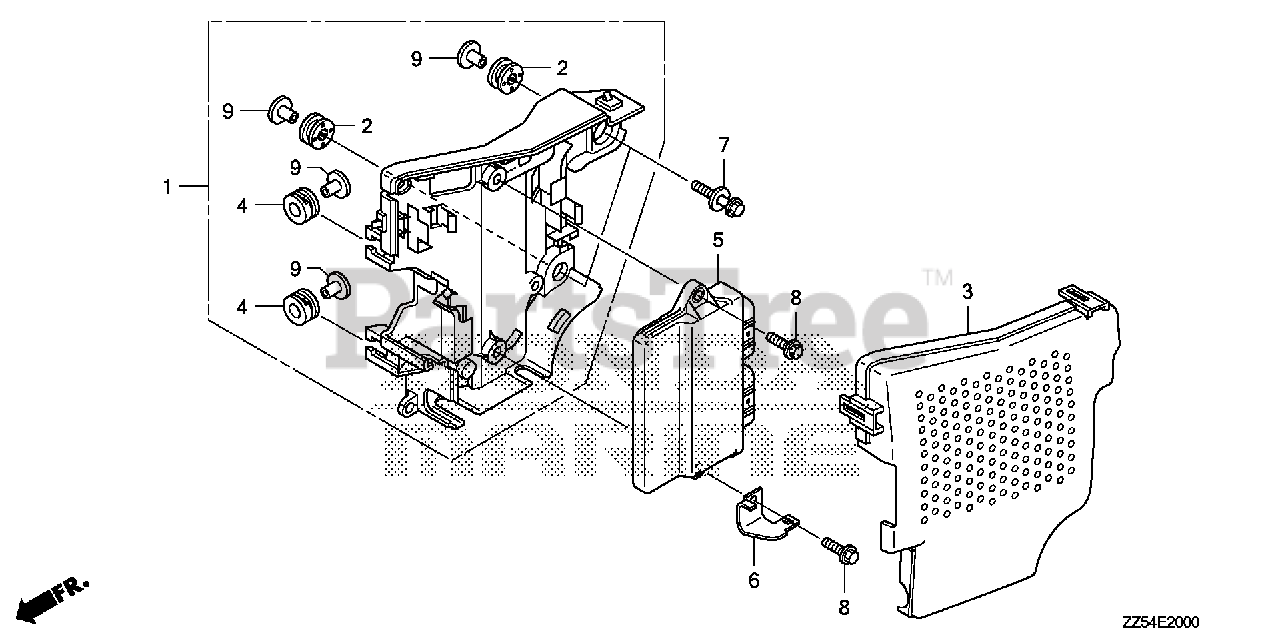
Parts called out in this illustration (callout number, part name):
1	CASE ASSY., ELECTRONIC PARTS
2	GROMMET, ELECTRONIC PARTS CASE
3	COVER, ELECTRONIC PARTS
4	GROMMET, MODULE IGNITION CONTROL CASE (CDI)(B)
5	CONTROL UNIT, ELECTRONIC
6	BRACKET, ELECTRONIC CONTROL UNIT
7	BOLT-WASHER (6X27) (CT200)
8	BOLT, FLANGE (6X20)
9	COLLAR, MODULE IGNITION CONTROL CASE (CDI)
